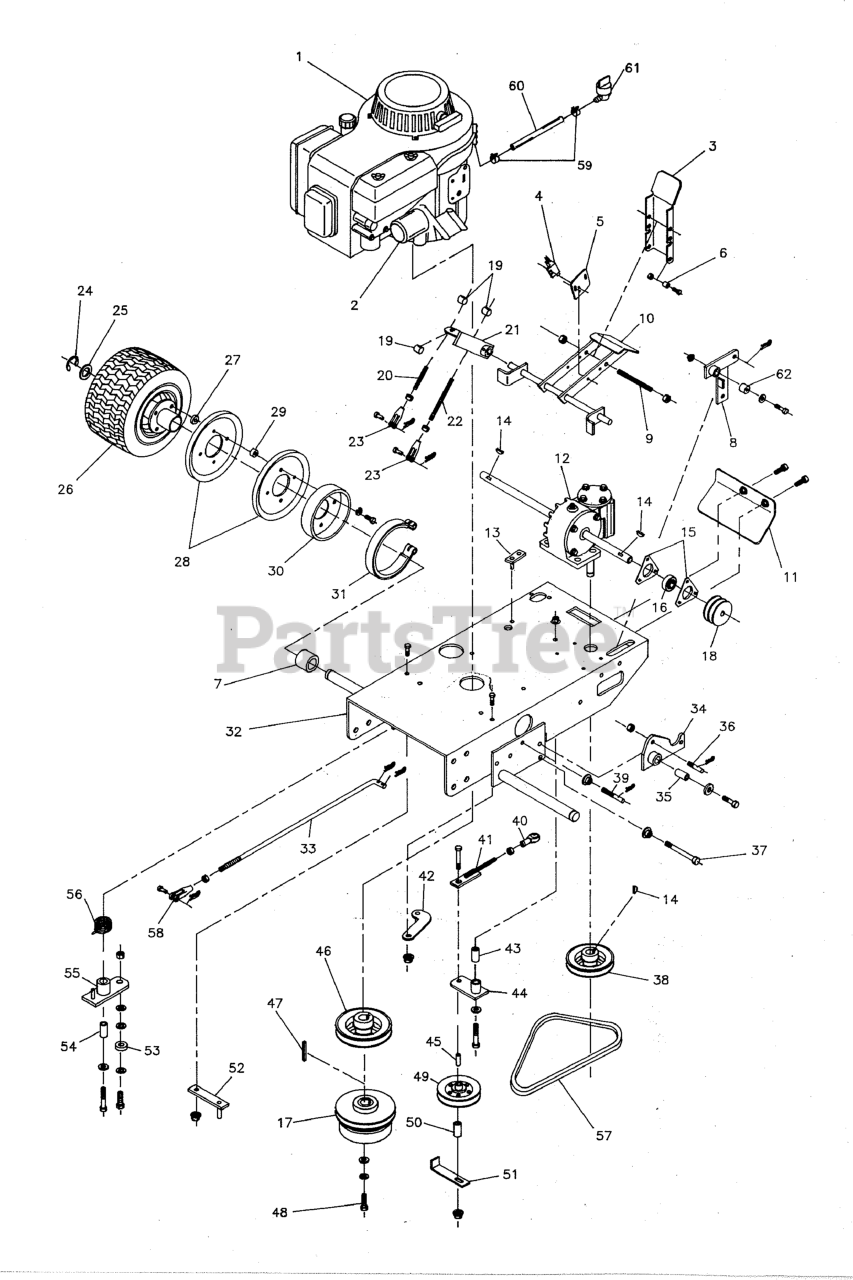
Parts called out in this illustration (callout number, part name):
2	OIL FILTER (49065-2078)
2	OIL FILTER (Briggs & Stratton)
3	Toe Plate
4	SWITCH, Plunger, NO
5	Switch Plate
6	SPACER, .26 X .38 X .50
7	SPACER, 1.00 x 1.50 x .94
8	Blade Clutch Pivot
9	BOLT, 5/16-18 x 4
10	Parking Brake Pedal
11	Skid Plate
12	Gear Box
13	Detent Tensioner
14	KEY, #61 Woodruff
15	Bearing Flange
16	5/8" Bearing
17	Variable Speed Pulley
18	PULLEY, Double-A Section
19	Barrel Nut
20	Clutch Adjustment rod
21	Pull Plate
22	Brake Adjustment Rod
23	CLEVIS, 5/16-24, Plastic
25	WASHER, 1" SAE
26	Wheel/Tire Assembly
27	SPACER, .33 x .88 x .25
28	PULLEY, Ground Drive
29	SPACER, Pulley
30	BRAKE DRUM
31	BRAKE BAND REPLACEMENT ASS'Y
32	Engine Deck Weldment
33	Blade Engagement Rod
34	Brake Lever Weldment
35	BUSHING, Brass
36	Threaded Pin
37	BOLT, 3/8-16 X 4" GD5 CZ
38	Gear Box Pulley
39	Brake Bank Pin
40	BALL JOINT 5/16-24 LH FEMALE W/STUD, BR
41	Connecting Rod
42	Belt Guide
43	BUSHING, Brass
44	Drive Idler Arm
45	Actuator Spacer
46	ENGINE PULLEY
47	KEY, 1/4 SQ. X 2-1/2
48	BOLT, M10 x 80MM
49	PULLEY, V-Idler
50	INSERT, Bearing
51	Belt Holder
52	Belt Guide
53	Bearing
54	BUSHING, Brass
55	Roller Cam
56	Torsion Spring
58	CLEVIS, 3/8-24, Plastic
59	CLAMP, Hose
60	4" Long Fuel Line
61	VALVE, Fuel Shut-Off
62	Bushing
